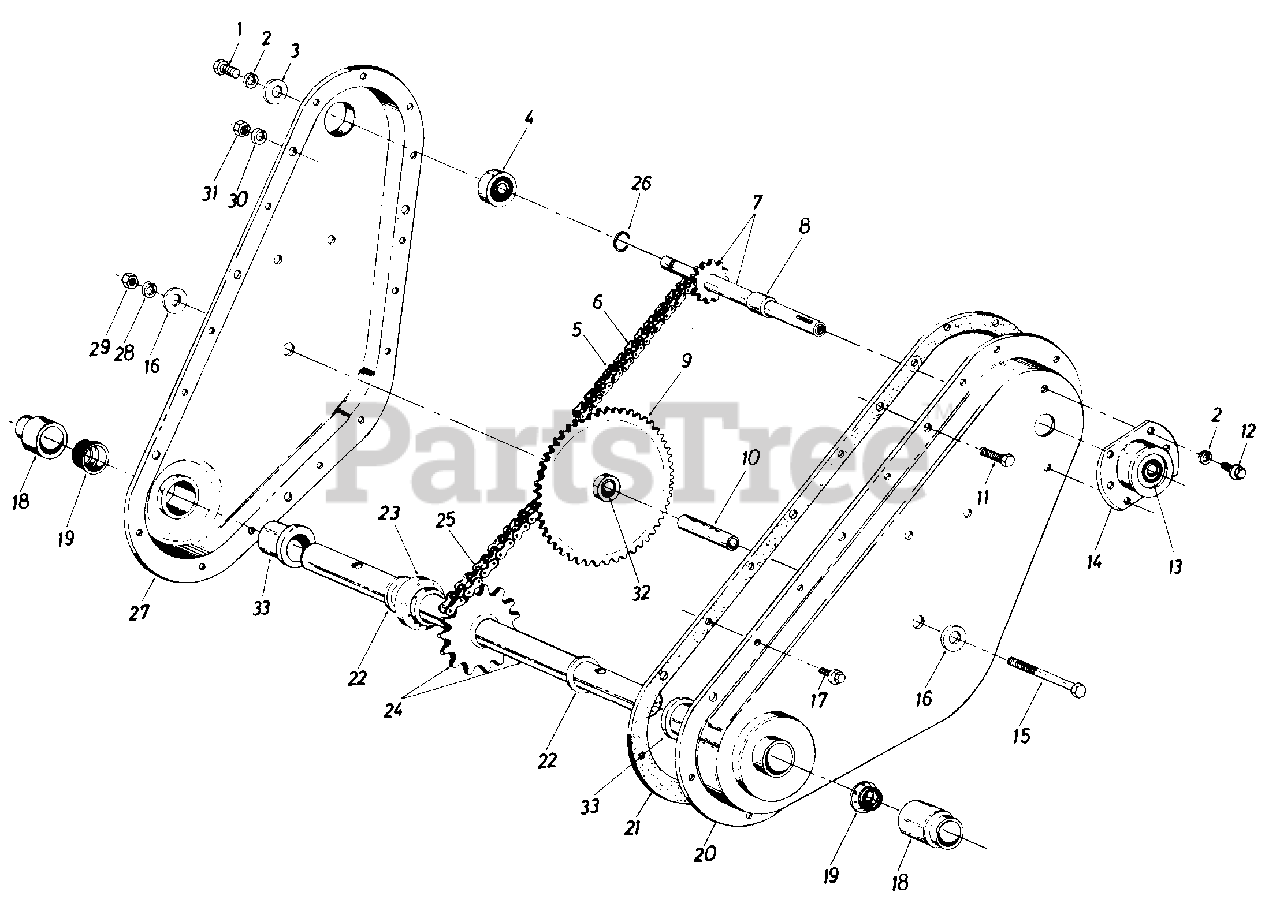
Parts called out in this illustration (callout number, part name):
1	Hex L-Scr. 1/4-28 x .625" Lg.
2	L-Wash. 1/4" I.D.*
3	Fl-Wash. .25" I.D. x .93" O.D. x .125" Thk.
4	Bearing .62" I.D. x 1.38" O.D. x .437" Thk.
5	#35 Chain 3/8" Pitch x 52 Links-Endless
6	Master Link
7	Input Shaft Assembly
8	Spacer
9	Sprocket Assembly
10	Sprocket Hub Tubing 3/8" I.D. x 5/8" O.D. x 1.9" Lg.
11	Hex Scr. 5/16-18 x .625" Lg.
12	Hex Wash. Hd. Self-Tap Scr. 1/4-20 x .50" Lg.
13	Bearing .625" I.D. x 1.38 O.D. x .437" Thk.
14	Bearing Housing
15	Hex Scr. 3/8-24 x 2.75" Lg.
16	Fl-Wash. 3/8" I.D. x 1.25" O.D. x .100 Thk.
17	Hex Wash. Hd. Self-Tap Scr. 1/4-20 x .50" Lg .
18	Dust Cap
22	Thrust Wash. 1.00" I.D. x .030" Thk.
23	Step Spacer
24	Tine Shaft Assembly
25	#50 Chain 5/8" Pitch x 46 Links-Endless
26	Snap Ring
29	Hex Nut 3/8-24 Thd.
30	L-Wash. 5/16" Scr.*
31	Hex Nut 5/16-18 Thd.*
32	Bearing
33	Bearing
14984-0638	HOUSING ASSEMBLY RH BLACK - MTD/TROY-BILT RED (0638)
